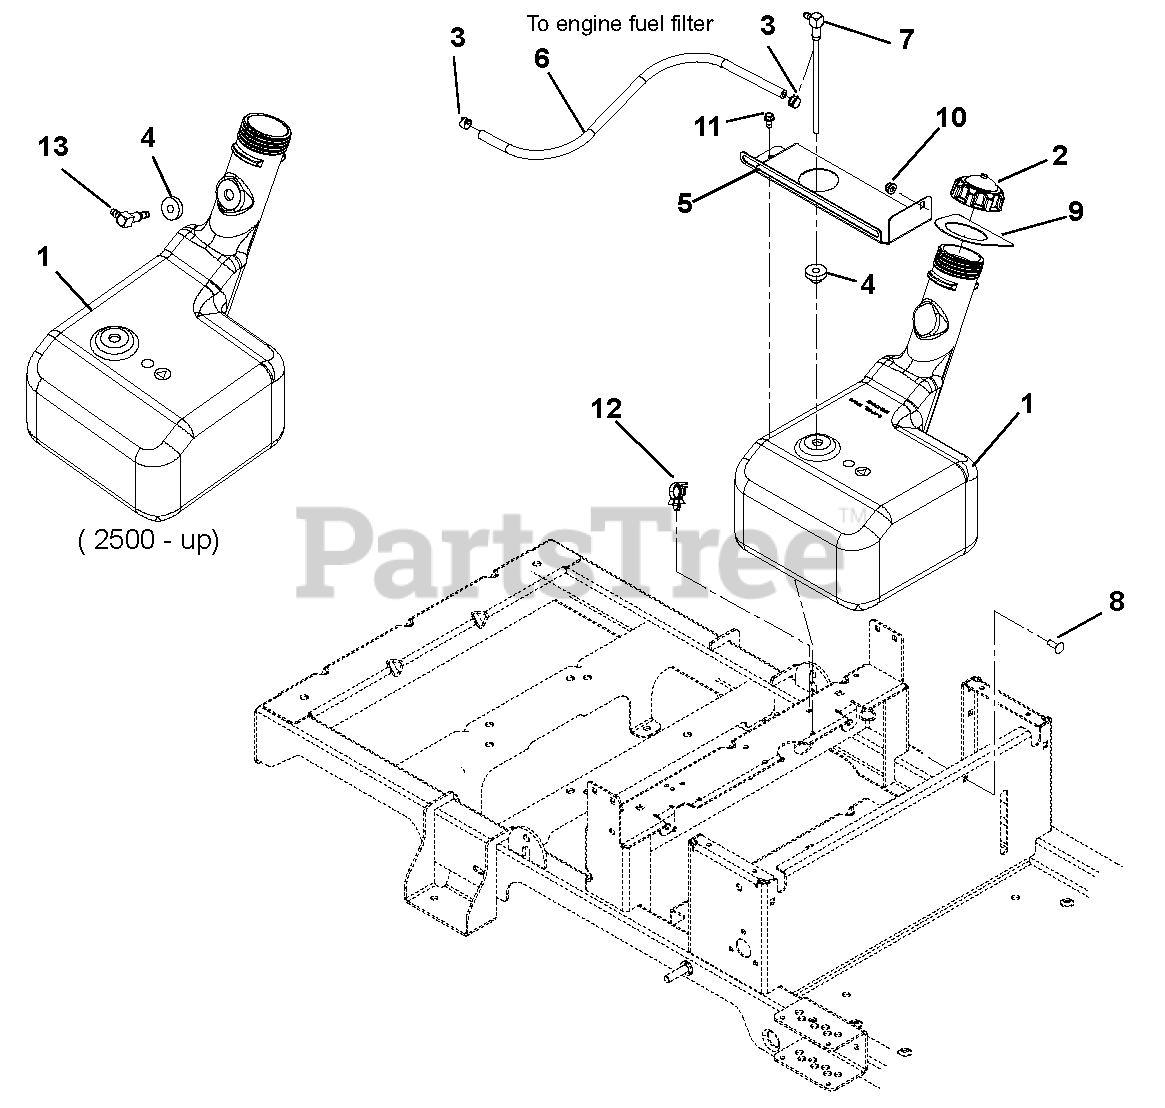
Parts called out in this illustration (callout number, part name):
1	Tank, Fuel (Serial Number 101 – 2499)
2	Fuel Cap (Serial Number 101 – 2499)
3	Clamp, Fuel Line
4	Bushing (Serial Number 101 – 2499)
5	Bracket, Tank Strap
6	Hose, .25 Low Perm Gas (as required)
7	Assembly, Fuel Pickup
8	Bolt, Round Head Square Neck .25-20 x .75
9	Seal, Tank Neck
10	Nut, .25-20 Nyloc Flange
11	Screw, Tapping .25-20 x .50 Hex Washer Head
12	Wire Clip
13	Fitting, 90 Degree Fuel Plastic (Serial Number 2500 – up)
